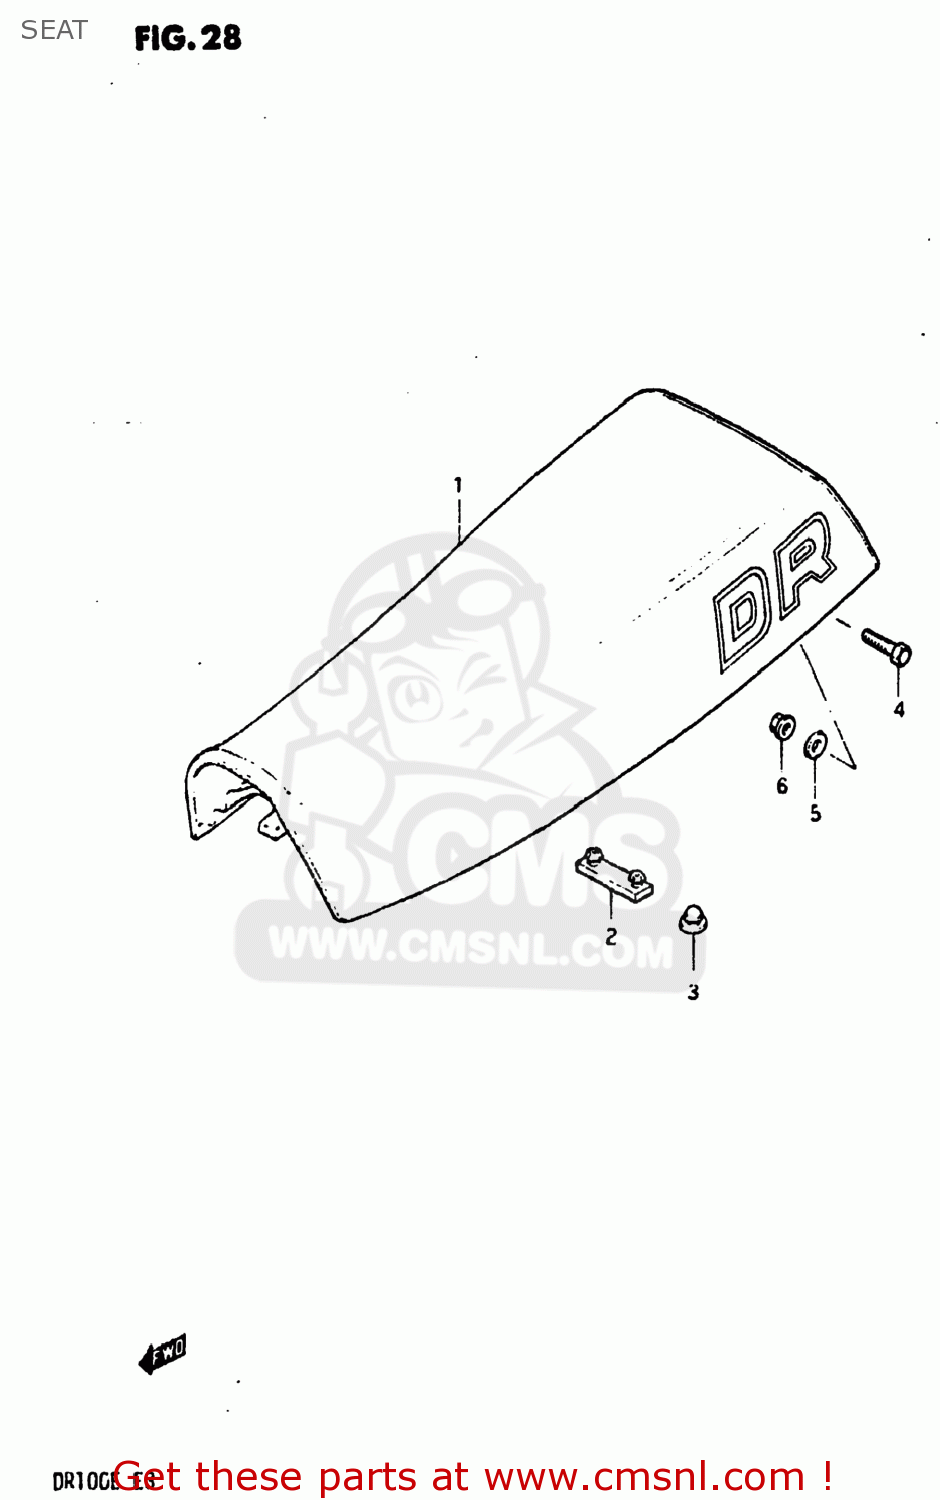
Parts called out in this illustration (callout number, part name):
1	SEAT ASSEMBLY
2	CUSHION
3	CUSHION
4	BOLT, LOWER
5	WASHER(8.5X23X1.2)
6	NUT
